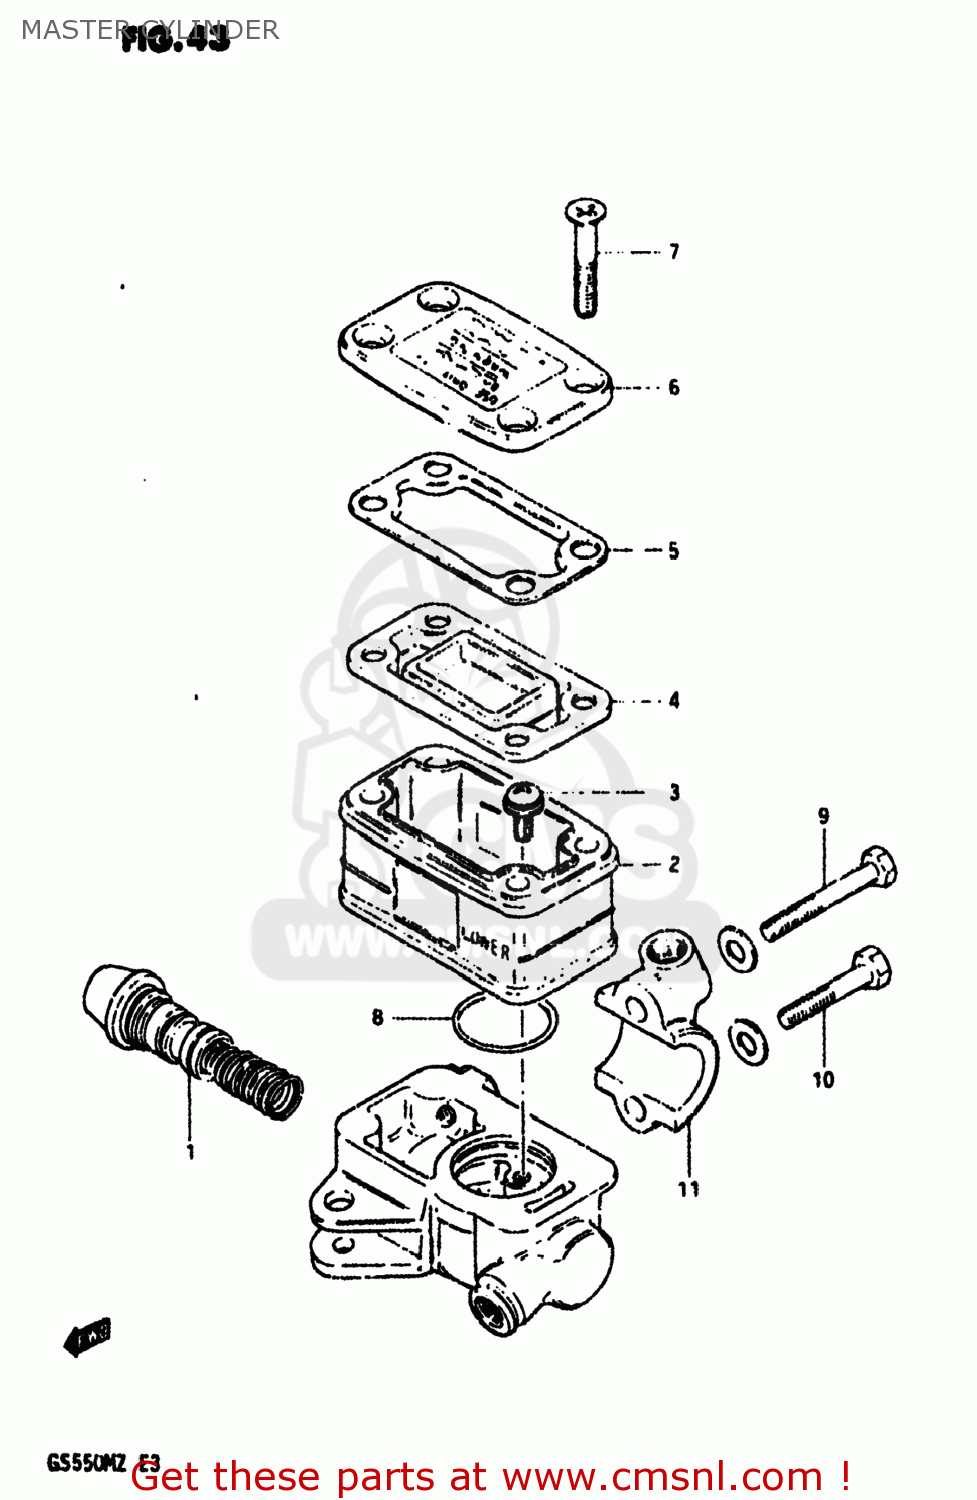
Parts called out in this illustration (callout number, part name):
1	PISTON & CUP SET
2	RESERVOIR
3	SCREW,MASTER C
4	DIAPHRAGM
5	SCREW,MASTER C
6	CAP
7	SCREW
8	O RING
9	BOLT,MASTER CYLINDER H
10	BOLT,MASTER CYLINDER H
11	HOLDER
